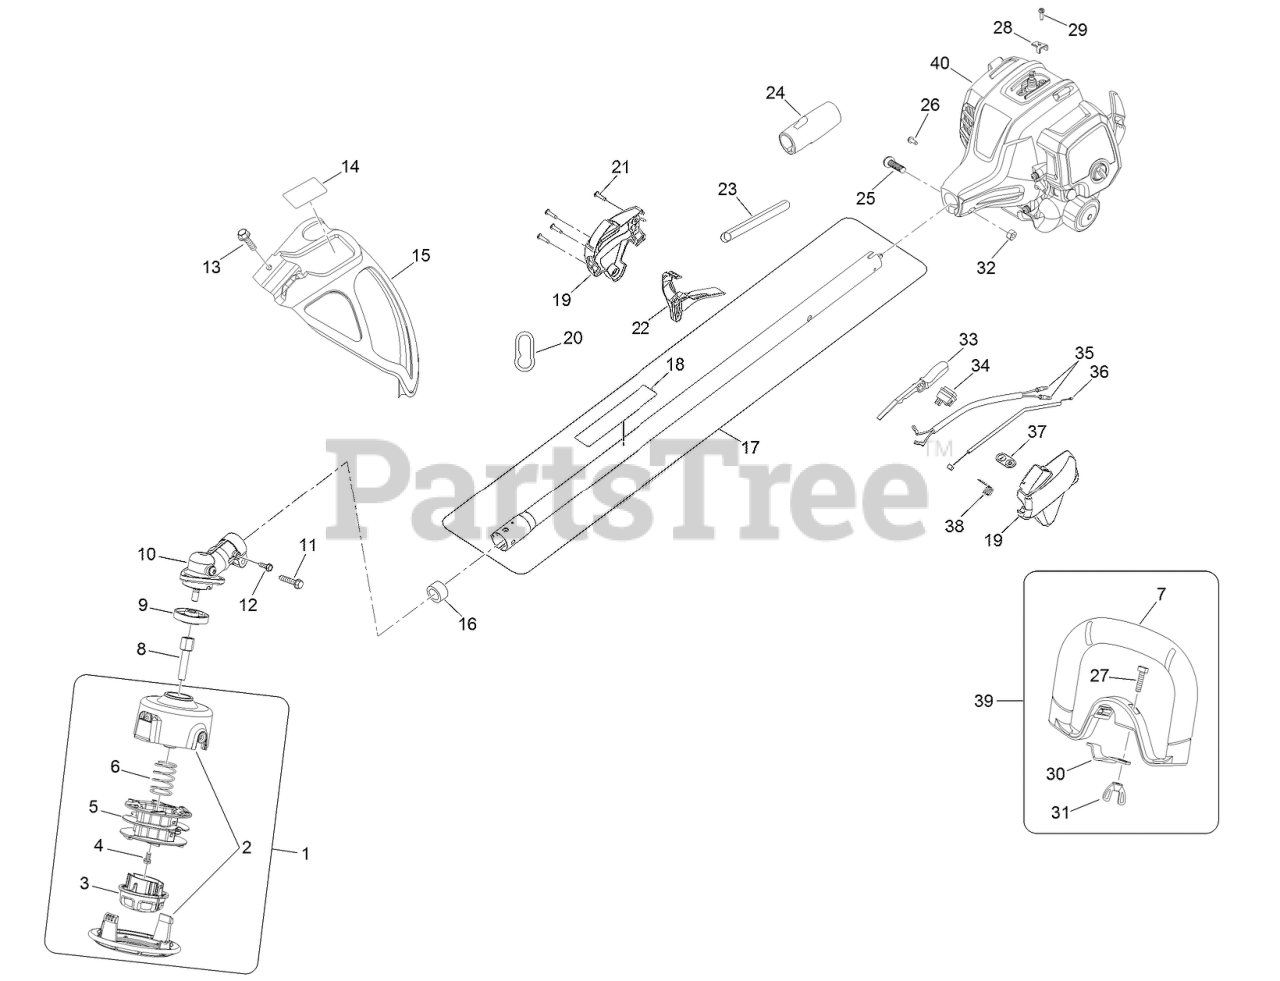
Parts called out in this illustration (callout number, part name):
1	SPOOL HEAD ASM
2	HOUSING-STRINGHEAD
3	KNOB-BUMP
5	SPOOL ASM
6	SPRING-COMPRESSION
7	HANDLE-SHAFT, UPPER
8	ADAPTOR-HEAD SHAFT, TRIMMER
9	WASHER-FLANGE
10	HEAD-GEAR
13	SCREW-HWH
14	DECAL-GRASS DEFLECTOR
15	GRASS DEFLECTOR ASM
17	UPPER BOOM ASM
18	DECAL-WARNING
19	CONTROL HANDLE ASM
20	CLIP-STRAP, SHOULDER
22	TRIGGER
23	TUBE-CORRUGATED
24	GRIP-SHAFT, UPPER
28	CLAMP-CABLE, THROTTLE
30	CLAMP-HANDLE, UPPER SHAFT
31	NUT-WING
32	NUT-HEX
33	LOCK-TRIGGER
34	SWITCH-ON/OFF
36	CABLE-THROTTLE
37	LABEL-ON/STOP
38	SPRING-TRIGGER
39	HANDLE ASM
40	POWERHEAD ASM
